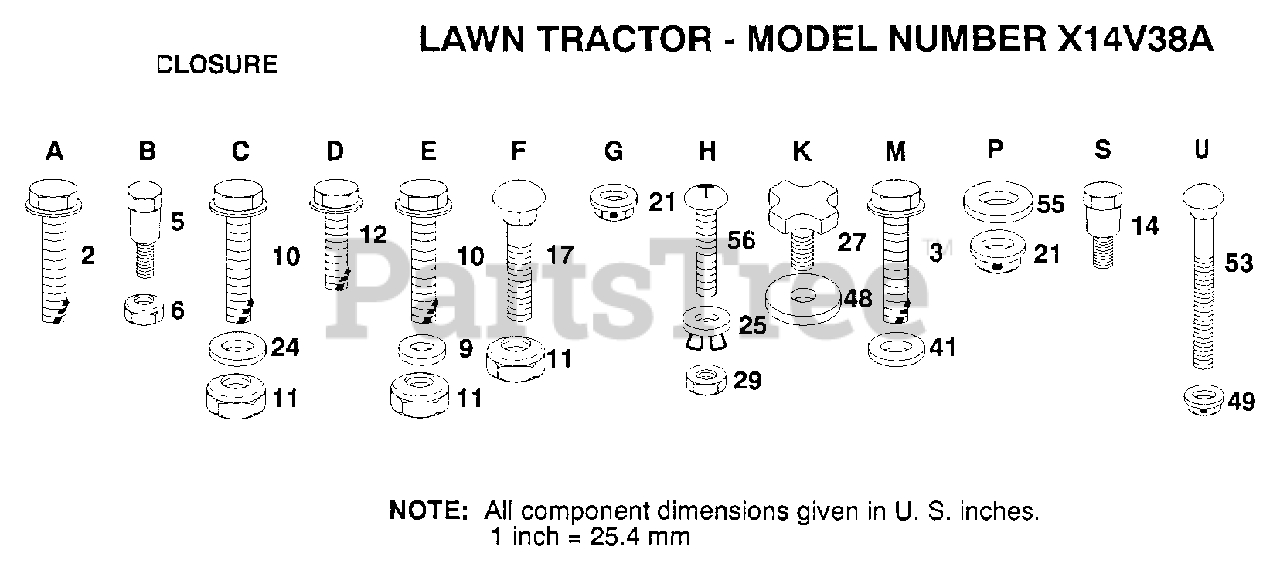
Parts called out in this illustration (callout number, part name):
2	SCREW
3	SCREW GTV
9	WASHER
12	SCREW LT
17	BOLT
21	PAL NUT LT
24	WASHER
25	RETAINER
27	"KNOB 1/2"" YT"
29	"GROMMET,PLASTIC"
41	WASHER
48	WASHER
53	BOLT
56	"SCREW,SPECIAL"
